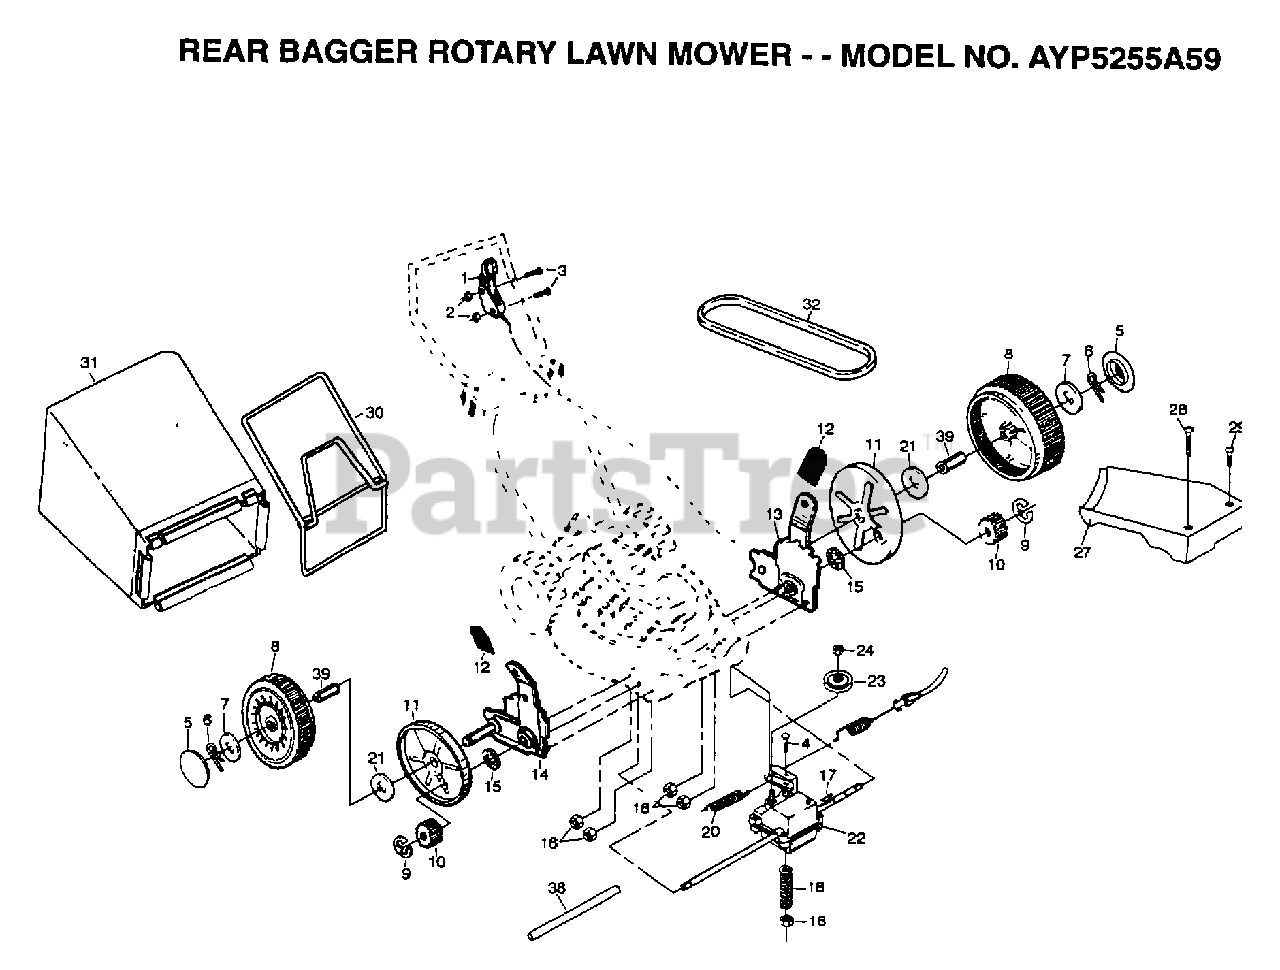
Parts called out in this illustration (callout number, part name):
1	CONTROL.DRIVE
2	LOCKNUT
3	SCREW
4	BOLT.1/4-20X2.0
5	HUB CAP
6	RETAINER CLIP PM
7	WASHER
8	WHEEL.8X2.LP.PR
9	E-RING.7/16.RE.
10	PINION.GEAR
11	DUST SHROUD PM
12	KNOB PM
15	WASHER PM
17	HI PRO KEY PM
18	SPRING.TENSION
20	SPRING
21	WASHER FLUT
23	PULLEY.DRIVEN
24	LOCKNUT
27	"COVER.DRIVE 22""RD"
30	CATCHER FRAME
31	GRASSBAG ASM
38	DRV SHAFT TUBE PM
39	BUSHING.HEX
